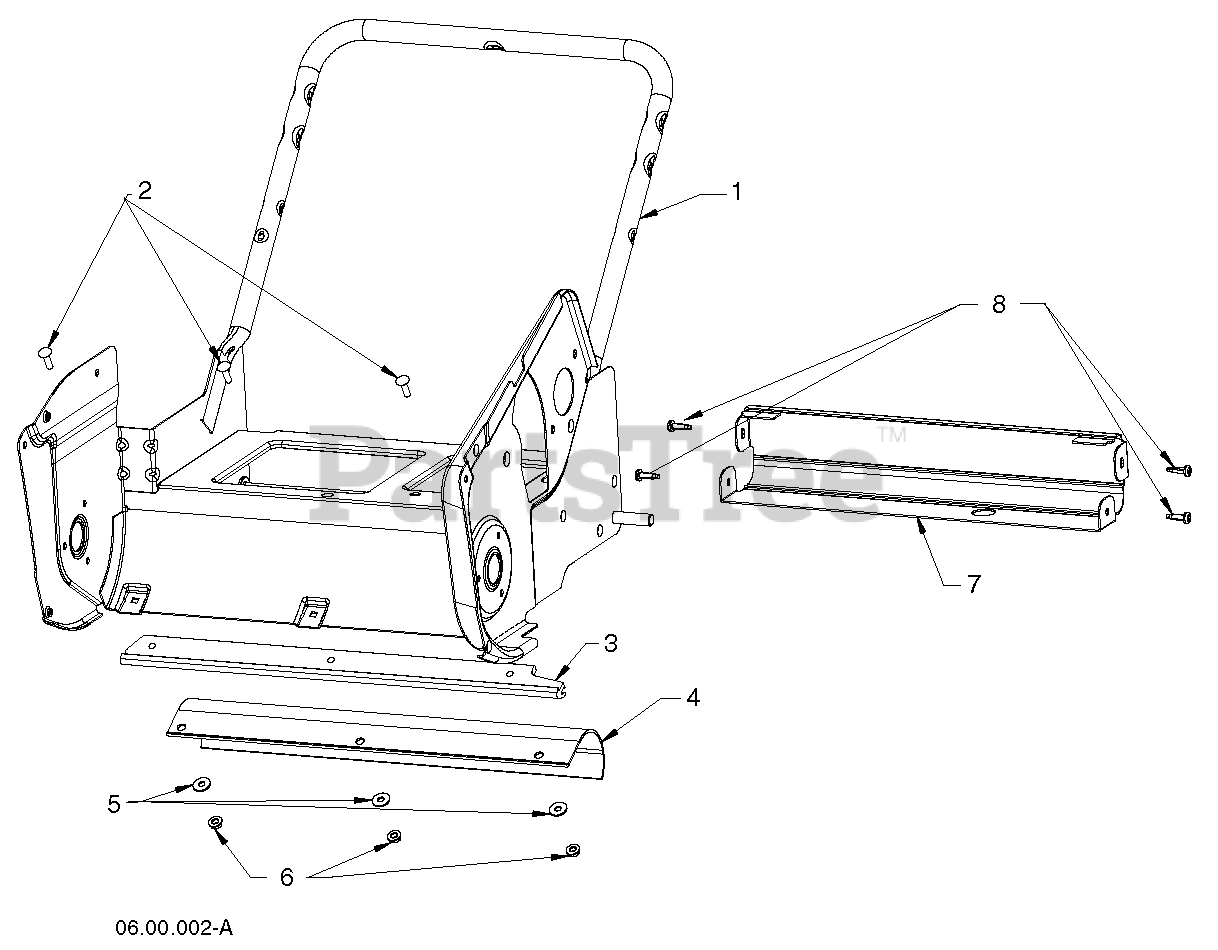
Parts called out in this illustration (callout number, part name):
1	FRAME.WELDMENT.GREY
2	BOLT.CARRIAGE.1/4-20 X 7/8
3	BAR.SCRAPER.SINGLE.STAGE.GREY
4	SKIRT.SCRAPPER-SSST
6	NUT.HEX.FLANGE.1/4
7	SUPPORT.SSST.REAR.FRAME.GREY
8	SCREW.PAN.HD.TORX.1/4-20X.750
